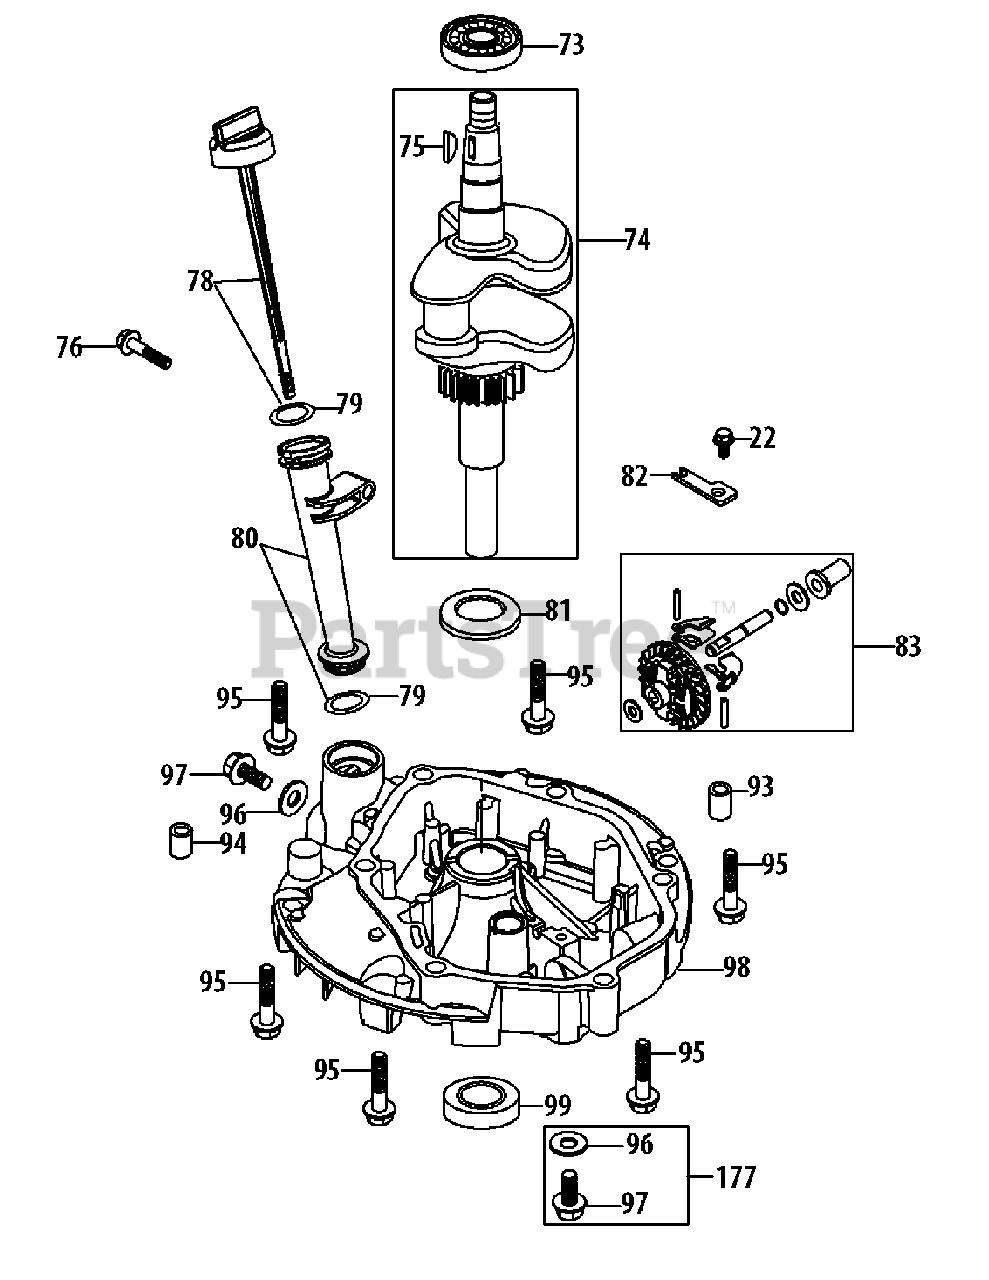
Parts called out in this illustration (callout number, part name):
22	Bolt M6×14
73	Main Bearing
74	Crankshaft Assembly
75	Woodruff Key
76	Bolt M6×35
78	Dipstick Assembly
79	Dipstick / Fill Tube O-Ring
80	Oil Fill Tube Asm
81	Crankshaft Thrust Washer
82	Governor Gear Mounting Plate
83	Governor Gear/Shaft Assembly
93	Dowel Pin 7×14
94	Dowel Pin 9×14
95	Bolt M8×50
96	Oil Drain Plug Washer
97	Oil Drain Plug
98	Crankcase Cover
99	Lower Crankshaft Seal
177	Oil Drain Plug And Washer Ass'Y
